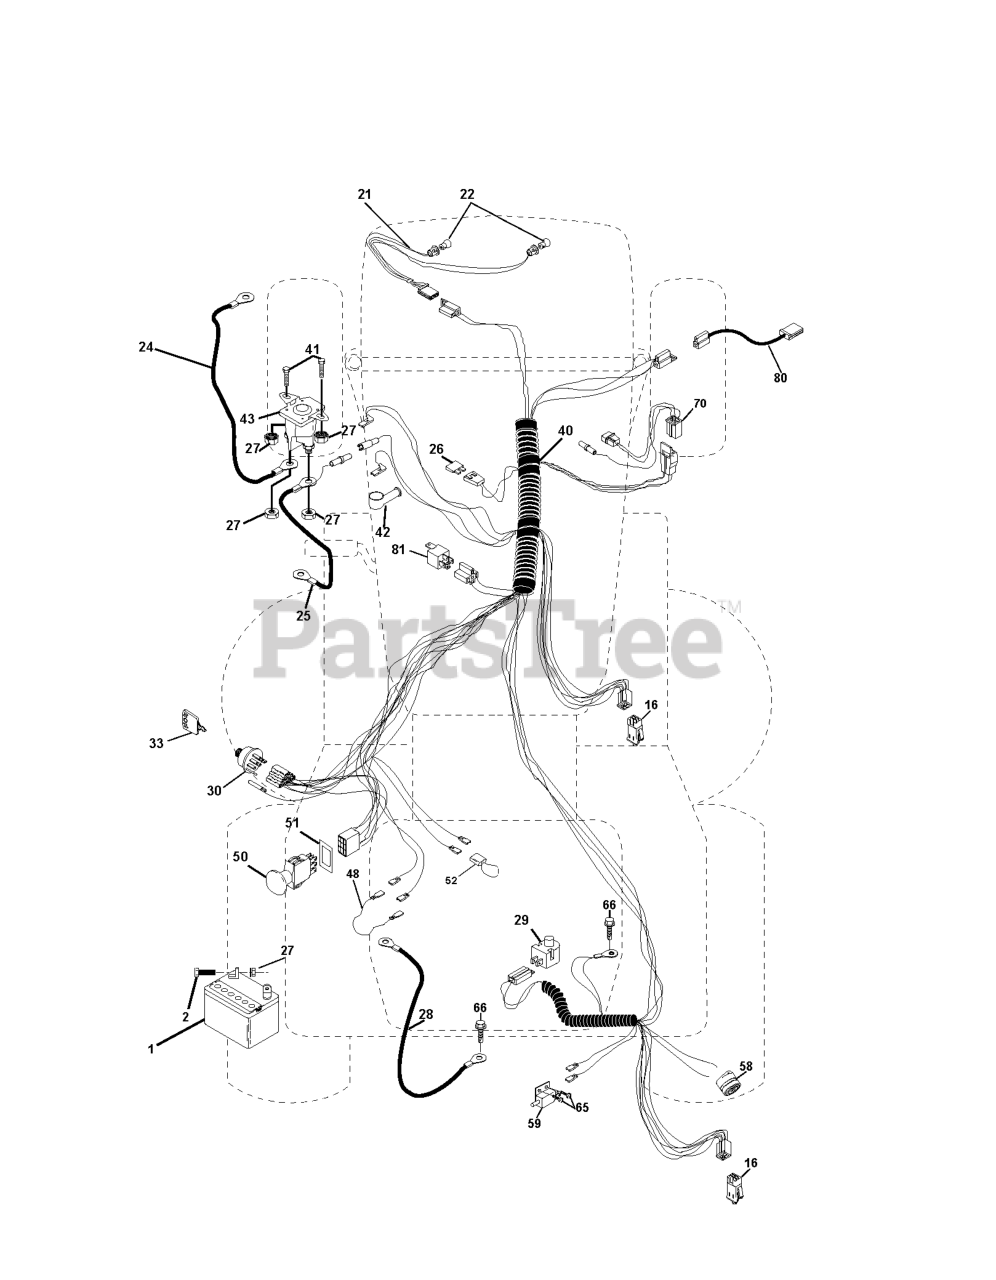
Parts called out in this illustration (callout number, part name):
1	BATTERY 12 VOLT 25 AMP
2	BOLT.HEX.1/4.X.3/4.DICHROMATE
16	SWITCH INTERLOCK
20	NUT
24	BATTERY CABLE GT
25	CABLE BATTERY
26	FUSE 15 AMP
27	NUT
28	CABLE GROUND
29	PLUNGER SWITCH (COLOR:OLIVE)
30	SWITCH IGN
33	KEY MLD GEN DELTA
40	HARNESS.ING.CRD.ELECT
41	BOLT
42	TERMINAL COVER
43	SOLINOID
48	ADAPTER.AMMETER
50	PTO SWITCH
51	FRAME RETAINING RING
52	WIRE PROTECTION LOOP
58	BUZZER
65	Screw, Hex Wsh. Tap #10-16 x 1/2
80	HARNESS, CLUTCH
81	RELAY.ASSY.T
